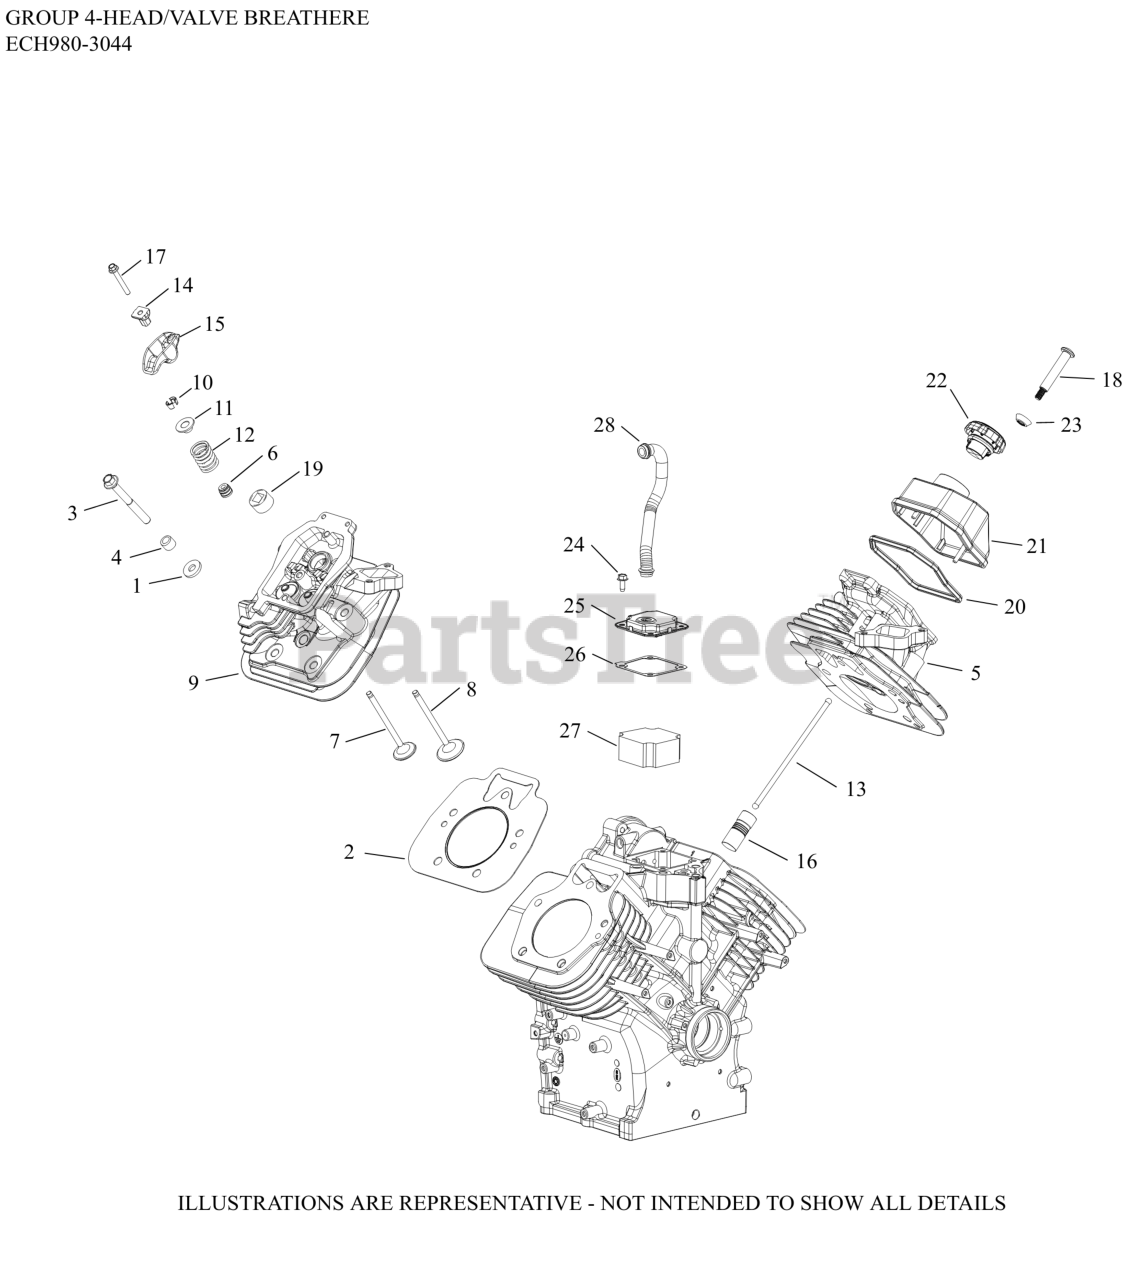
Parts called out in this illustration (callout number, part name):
1	WASHER, FLAT 13/32"
2	KIT, CYLINDER HEAD GASKET
3	SCREW, FLG M10X1.5X90
5	KIT, HEAD CYLINDER #1-(#6281801S)
6	SEAL, VALVE BAND
7	VALVE, EXHAUST
8	VALVE, INTAKE
9	KIT, HEAD CYLINDER #2
10	KIT, RETAINER
11	CAP, VALVE SPRING
12	SPRING, VALVE
13	ROD, PUSH
14	PIVOT, ROCKER ARM
15	ARM, ROCKER
16	LIFTER, VALVE HYDRAULIC-USE 25 351 11-S
17	SCREW, HEX FLANGE (SILVER) M6X1.0X45
18	SCREW, SHOULDER
19	PLUG, PIPE 3/4 NPTF SQUARE
20	SEAL, VALVE COVER
21	KIT, COVER, VALVE (OIL FILL)
22	CAP ASSEMBLY
23	GROMMET, VALVE COVER SCREW
24	SCREW, THREAD FORMING
25	KIT, BREATHER ASSEMBLY
26	GASKET, BREATHER
27	FILTER, BREATHER
28	HOSE, BREATHER H/S
